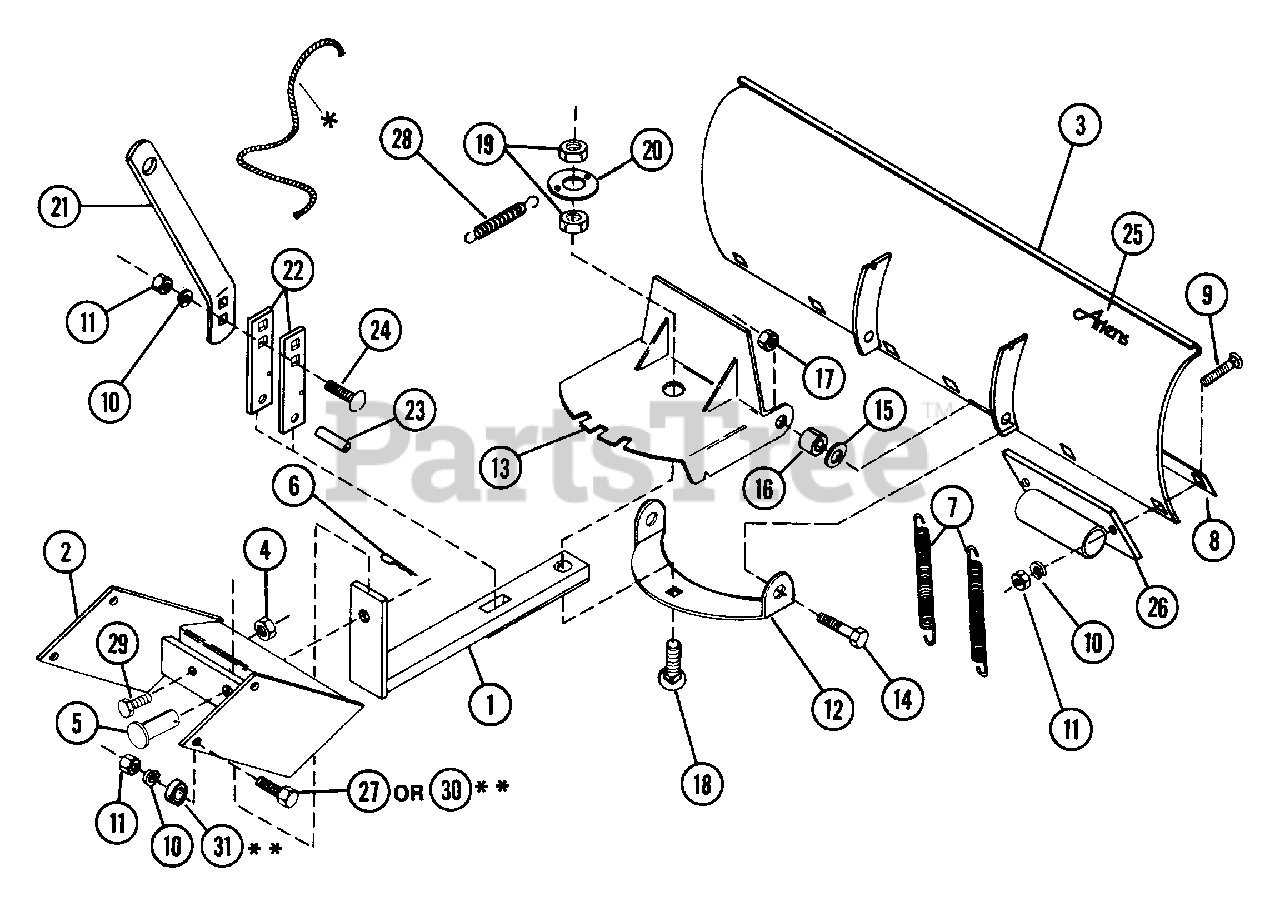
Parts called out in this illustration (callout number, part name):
1	DOZER BLADE FRAME
2	40 INCH SNOW BLADE
3	PUSH TUBE ASSEMBLY
4	NUT-LK-CTR .375-16 GR A PL
5	CLEVIS PIN
6	PIN-HAIR INT .09X.62X2.25
7	SG-TENS .125X.81X6.50 WLD 10
8	WEAR BAR
9	BLT-RDHDSQSHNK .38-16X1.00 PL
10	WSHR-LK .375X.115 HVY PL
11	NUT-HEX .375-16
12	LOWER PIVOT PLATE
13	UPPER PIVOT PLATE
15	WSHR-FL-STL .531X1.062X.095 PL
16	PIVOT BUSHING
17	NUT-LK-CTR .50-13
18	BLT-RDHDSQNK .75-10X3.0
19	NUT-JAM .75-10 PL
20	LATCH SPRING WASHER
21	PIVOT BLOCK EXTENSION
22	BAR PIVOT LOCK
23	PIN-ROLL .250X1.00
24	BLT-RDHDSQNK .38-16X1.25 PL
25	ARIENS SCRIPT DECAL
27	BLT-HEX .38-16X1.00 PL
28	SG-TENS .106X.56X2.75 WLD 10
29	BLT-HEX .38-16X1.50 PL GR2
30	BLT-HEX .31-18X2.00 PL GR2
31	SPACER .63 X .38 X .75
